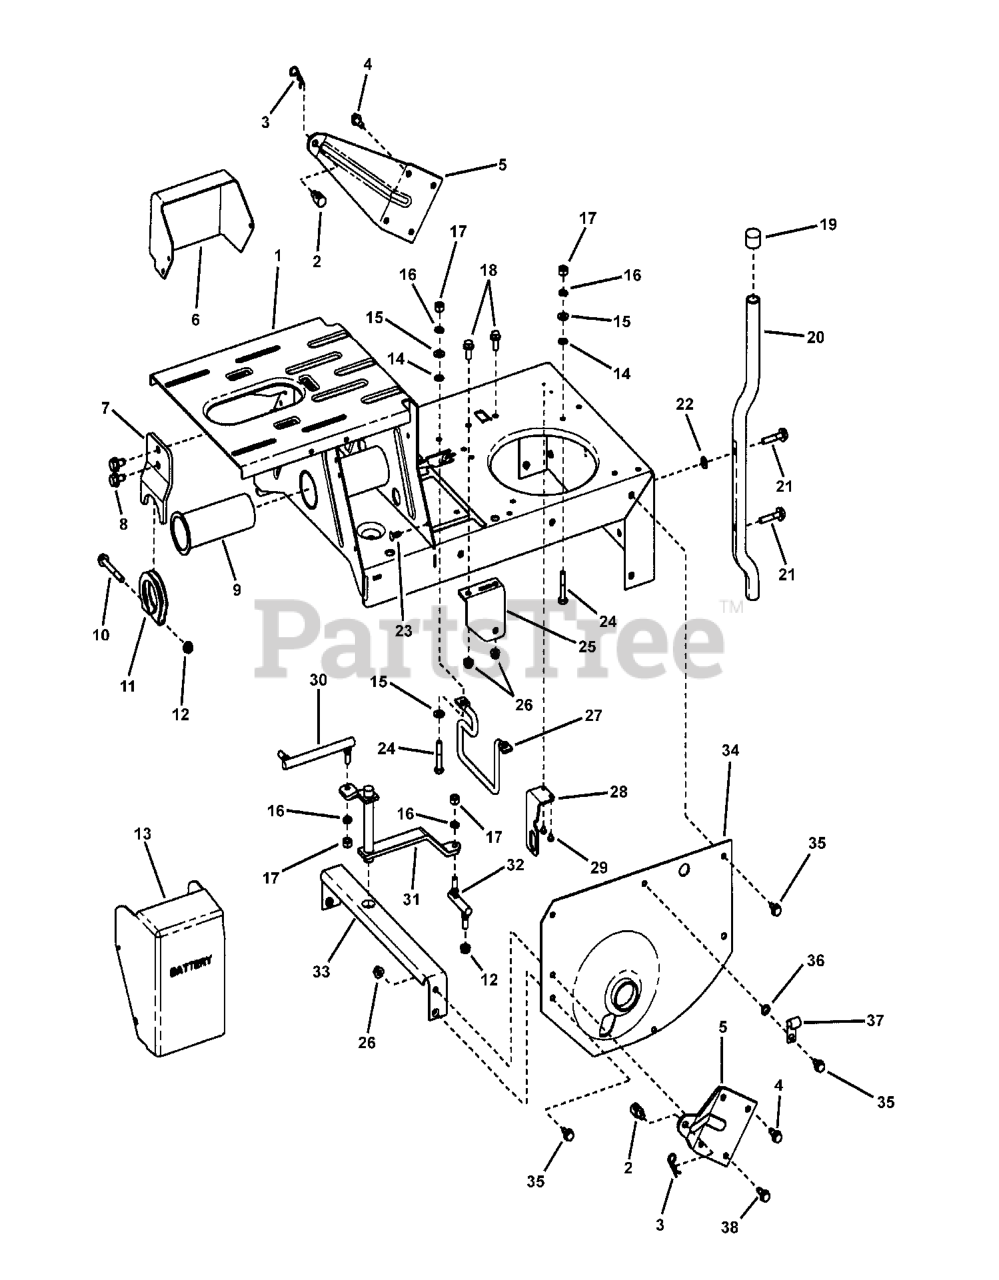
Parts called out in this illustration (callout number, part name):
1	WELDMENT, Main Case (Standard)
2	SWIVEL, Adjustable
3	HAIR PIN, 3/32 x 1-1/2"
4	SCREW, 5/16-18 x 3/4" Hex Washer Self-Tap
5	WING, Rear
6	COVER, Solenoid
7	BRACKET, Belt Adjuster
8	SCREW, 3/8-16 x 5/8" Hex Washer Self-Tap
9	BUSHING, Pivot
10	SCREW, 5/16-24 x 2-1/2" Hex Head Cap, GR 5
11	TUBE CLAMP
12	NUT, 5/16-24 Flange Lock (Large)
13	COVER, Battery
14	RETAINER, 5/16" Bolt
15	WASHER, 5/16" Flat
16	WASHER, .32 x .58 x .08 Split Lock
17	NUT, 5/16-24 Hex, GR 5
18	BOLT, 5/16-18 x 3/4" Hex Flange Lock, GR 5
19	CAP, Bumper
20	BUMPER, Rear
21	SCREW, 5/16-18 x 1-1/2" Hex Washer Self-Tap
22	WASHER, 11/32" Flat
23	FASTENER, 1/4" Ratchet
24	SCREW, 5/16-24 x 1-3/4" Hex Head Cap, GR 5
25	BRACKET, Drive Support
26	NUT, 5/16-18 Hex Flange Lock, GR 5
27	BELT GUIDE, 25, 26, 28, 41" (5.74" Bolt Pattern, 4.74" Belt Gap)
28	BRACKET, Switch
29	SCREW, #10-32 x 1/4" Hex Washer Self-Tap
30	SHIFT LINK, Long (5/16-24 both ends)
31	WELDMENT, Shift Arm
32	SHIFT LINK, Short (5/16-24 thread)
33	CROSS BRACE
34	FENDER, Left Hand (1.628" I. D. Hole)
35	SCREW, 5/16-18 x 5/8" Hex Washer Self-Tap
36	WASHER, 5/16" Internal Tooth Lock
37	CLIP, Wire
38	SCREW, 5/16-18 x 3/4" Hex Head Cap, GR 5
